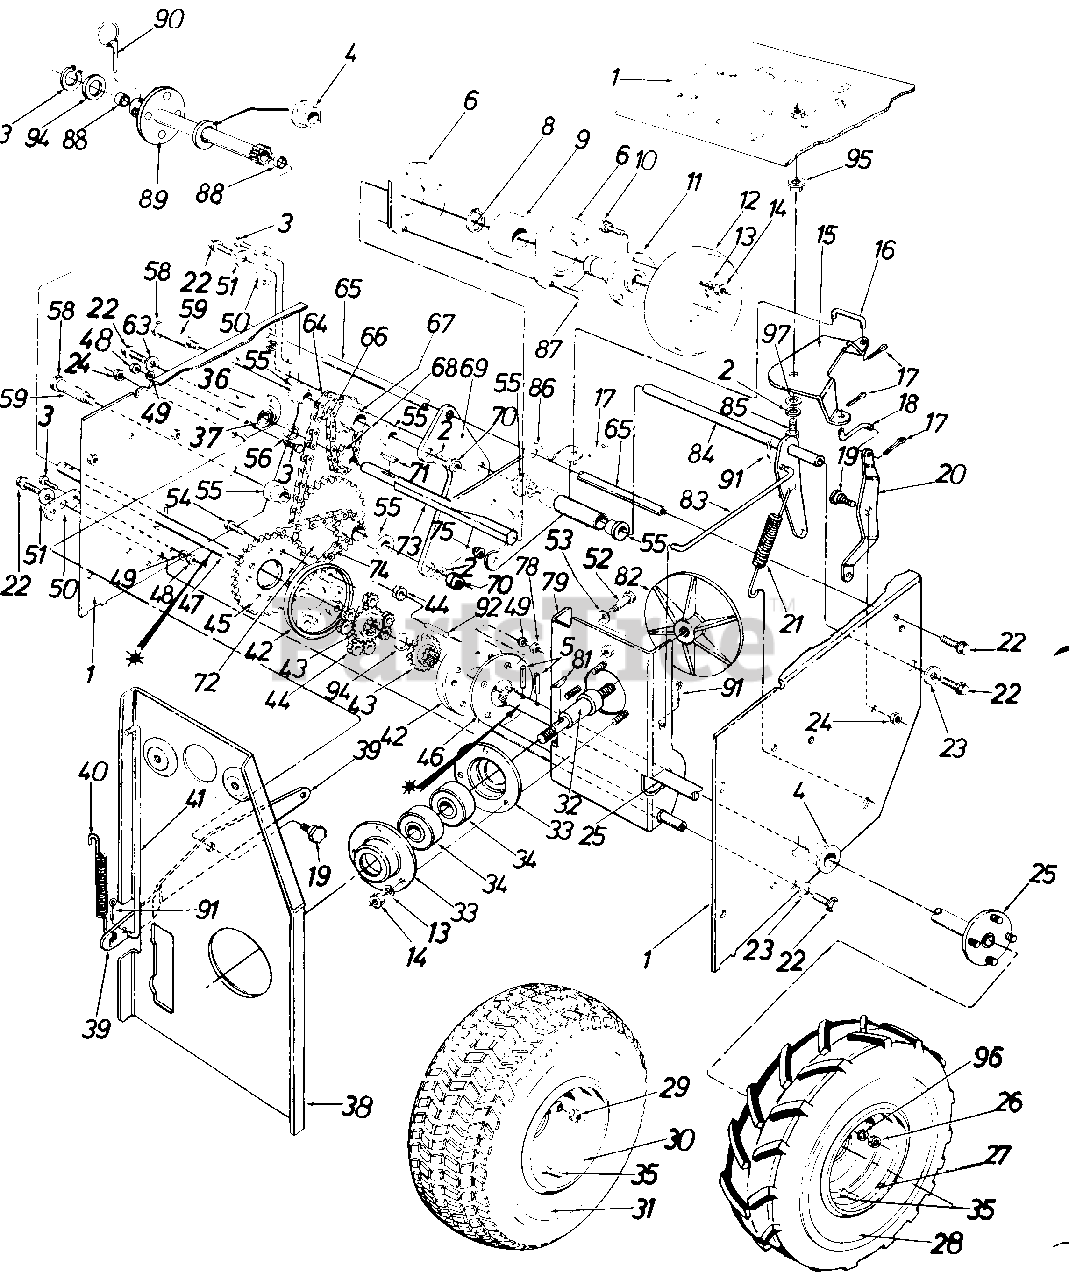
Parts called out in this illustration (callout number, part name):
1	Frame Ass'y.
2	L-Wash. 3/8" I.D.
3	Hex Bolt 1/4-20 x .62" Lg.*
4	Flange Brg. w/Flats 1.00" I.D.
5	H-Spring Pin Spiral 3/16" Dia. x 1.25" Lg.
6	Bearing Housing
8	Snap Ring-1.00" Dia.
9	Ball Brg. 25 mm x 52 mm x 15 mm Thk.
10	Hex Sems Scr. 5/16-18 x .75" Lg . *
11	Friction Wheel Adapter
12	Friction Wheel Ass'y.
13	L-Wash. 5/16" Scr.
14	Hex Nut 5/16-18" Thd.
15	Sliding Linkage Brkt.
16	Sliding Rod-.31" Dia. x 2.00" Lg.
17	Cot. Pin 3/32" Dia. x .75" Lg.
18	Shifting Linkage Rod .31" Dia. x 2.25" Lg.
19	Shld. Scr. .625" Dia. x .170"
20	Shifting Linkage Brkt.
21	Extension Spring .73 O.D. x 4.31" Lg .
22	Hex L-Scr. 5/16-18 x .62" Lg.
23	Fl-Wash. .345 I.D. x .75 O.D.
24	Hex Cent. L-Nut 3/8-16 Thd.
25	Differential Shaft Ass'y.-L.H.
26	Hex Nut 3/8-16 Thd.
27	Wheel Rim Ass'y.
28	Wheel Ass'y. Comp. 16.0 x 4.80-8
29	Cone Nut 3/8-24 Thd.
30	Wheel Rim Ass'y.
31	Wheel Ass'y. Comp. 16.0 x 6.50
32	Drive Plate Spindle
33	Bearing Housing
34	Ball Brg. .787 I.D. x 1.85 O.D.
35	Air Valve
36	Bearing Housing
37	Ball Bearing
38	Engine Brkt. Ass'y.
39	Auger Clutch Brkt.
40	Extension Spring .38 O.D. x 3.18" Lg.
41	Auger Clutch Rod .31" Dia. x 10.62" Lg.
42	Differential Housing
43	20 Tooth Spur Gear
44	9 Tooth Spur Gear
45	28 Teeth Sprocket
46	Differential Hsg. Support Plate
47	Differential Connecting Shaft
48	Hex Nut 1/4-20 Thd.
49	L-Wash. 1/4" Scr.
50	Pivot Axle Brkt.
51	Fl-Wash. .345" I.D. x .75" O.D.
52	Shld. Scr.
53	Bell-Wash.
54	Hex Scr. 1/4-28 x 1.75" Lg.
55	Flange Brg.-.630" I.D.
56	Spacer. 51" I.D. x .69" O.D.
58	Hex Scr. 3/8-24 x 2.75" Lg.
59	Sprocket Hub Tubing 1.900" Lg.
63	Bell-Wash. .345" I.D. x .88 O.D.
64	#41 Chain-1/2" Pitch x 43 Links
65	Sliding Support Axle
66	#41 Chain 1/2" Pitch x 19 Links
67	9 and 14 Teeth Sprocket Hub Ass'y.
68	8 Teeth Sprocket
71	#9 Hi-Pro Key 3/32 x 5/8" Dia.
72	9 and 32 Teeth Sprocket Hub Ass'y.
73	Hex Shaft
74	#420 Chain-1/2" Pitch x 37 Links
75	Hex Ins. Jam L-Nut 1/4-28"
78	Hex Nut 1/4-28 Thd.
82	Aluminum Drive Plate
83	Drive Clutch Rod .31" Dia. x 7.38" Lg.
84	Drive Clutch Brkt. Ass'y.
85	Hex Scr. 3/8-16 x 1.00" Lg.
86	Sliding Brkt. Ass'y.
87	Hex Scr. 1/4-28 x .62" Lg.
88	Sleeve Brg.
89	Differential Tubing Ass'y.-R.H.
90	Klick Pin 1/4" Dia. x 1.75" Lg.
91	Internal Cot. Pin 5/16 Dia.
92	Differential Pin
93	Snap Ring .625 Shaft
94	Fl-Wash. .62 I.D. x 1.25 O.D.
95	Shld. Spacer 5/8" I.D.
96	L-Wash. 3/8" I.D.
97	Fl-Wash.
